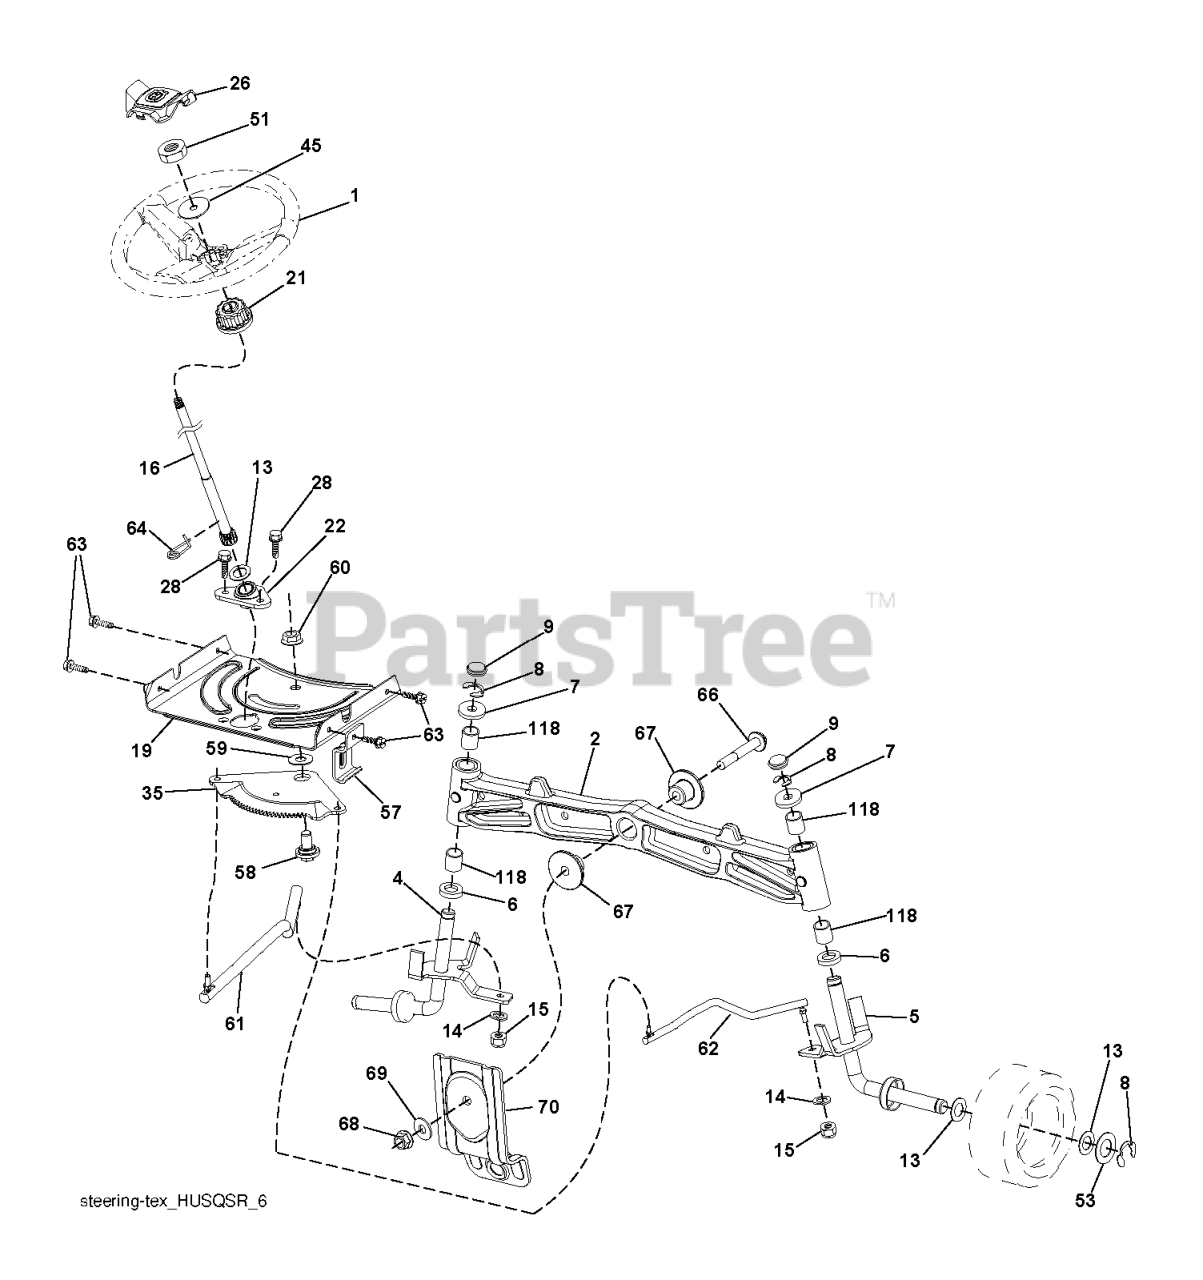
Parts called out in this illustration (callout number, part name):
1	RP WHEEL.STEER.HUSQ.PREM.OVMLD
2	AXLE.SVC.ASM CAST IRON.TEX
4	SPINDLE.WELDED.LH.15"TEX
5	SPINDLE.WELDED.RH.15"T
6	THRUST WASHER
9	CAP.SPINDLE.BLACK
14	WASHER, LOCK 3/8
15	NUT CROWNLOCK 3/8-24
16	SHAFT.STEER.STEALTH.DD
19	PLATE.STEER.DDL.NLT/NG
21	ADAPTER, WHEEL STNG..
22	BUSHING.ASM.STEERING.A
26	RP INSERT.CAP.WHL.STRG.HUSQ.
28	SCREW, 3/8-16X3/4
35	GEAR.SECTOR.PLATE.DDL.
45	WASHER 9/16"ID, 2 3/8"OD
51	NUT.HEX.1/2-20
53	WASHER.HARDENED
57	BRACKET.UPSTOP.TEX
58	BOLT.SHOULDER.SECTOR.P
59	WASHER.THURST.SECTOR.S
60	NUT FLANGE LOCK 5/8-11
61	DRAGLINK.LH.BALLSTUD.D
62	DRAGLINK.RH.BALLSTUD.D
63	SCREW
64	RETAINER.CLIP.SPRING.S
66	BOLT HEX FGHD 7/16-14 X 3 SERR
67	BUSHING.PM.FRONT AXLE
68	NUT.LOCK.FLANGE.7/16
69	WASHER.1.5X.505X.118
70	BRKT.DECK.SUSPENSION.F
118	BUSHING, AXLE CAST
